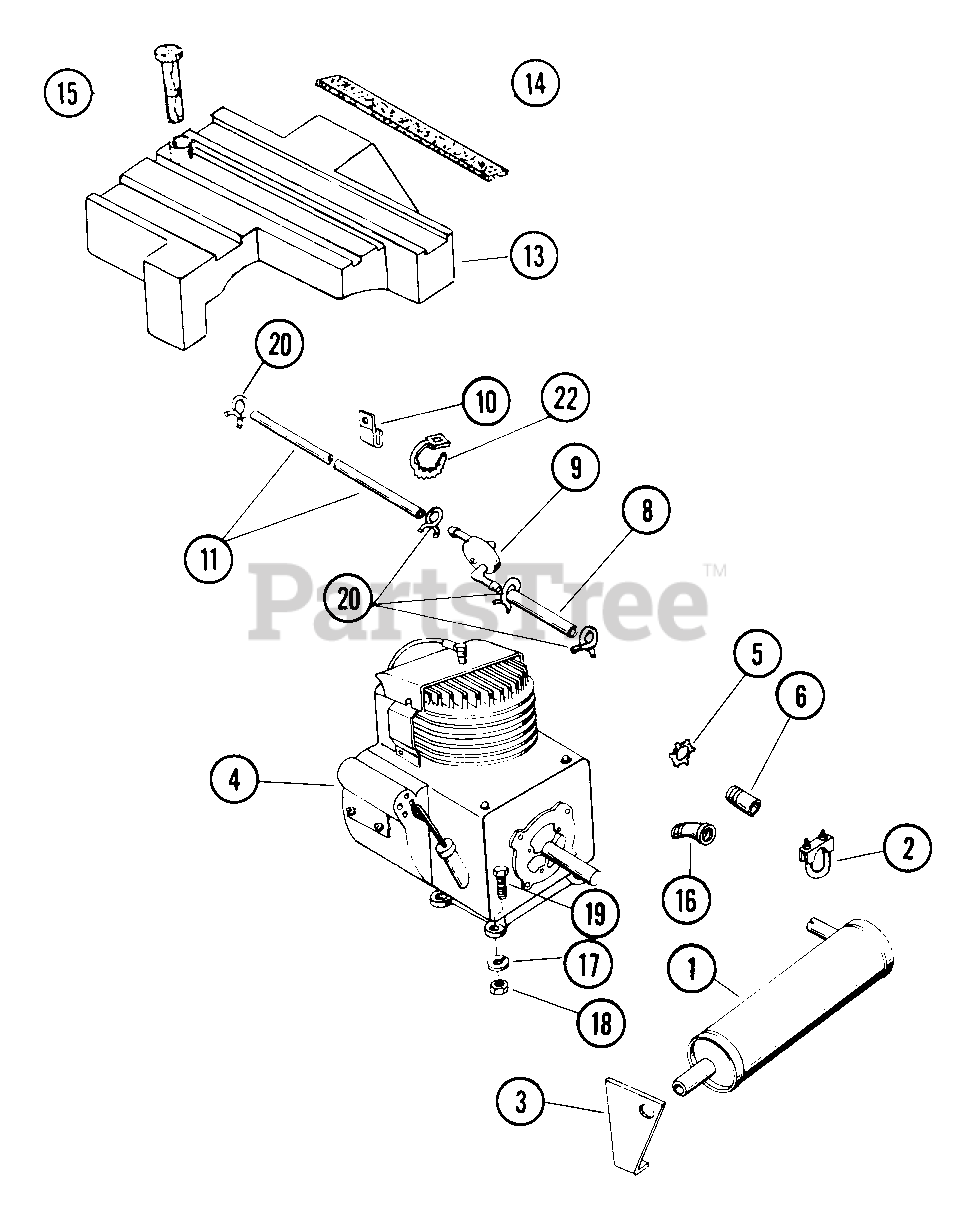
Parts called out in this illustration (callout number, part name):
1	MUFFLER
2	EXHAUST CLAMP
2	EXHAUST CLAMP - 1 3/4
3	MUFFLER BRACKET
5	NUT-LK CONDUIT 1.00
5	NUT-LK CONDUIT 1.25
6	PIPE
6	PIPE NIPPLE
8	HOSE
9	FUEL FILTER
10	J-CLAMP
11	1 INCH OF 031537 GAS LINE HOSE
13	TANK
13	GAS TANK
14	FELT STRIP
15	GAS GAUGE & CAP
16	STREET ELBOW 1-1/4 X 45 DEGREE
17	WSHR-LK .375X.094 MED PL
18	NUT-HEX .375-16
19	BLT-HEX .38-16X1.50 PL GR5
20	CLAMP-HOSE WIR.490/.510X.092#8
21	TIE DOWN
